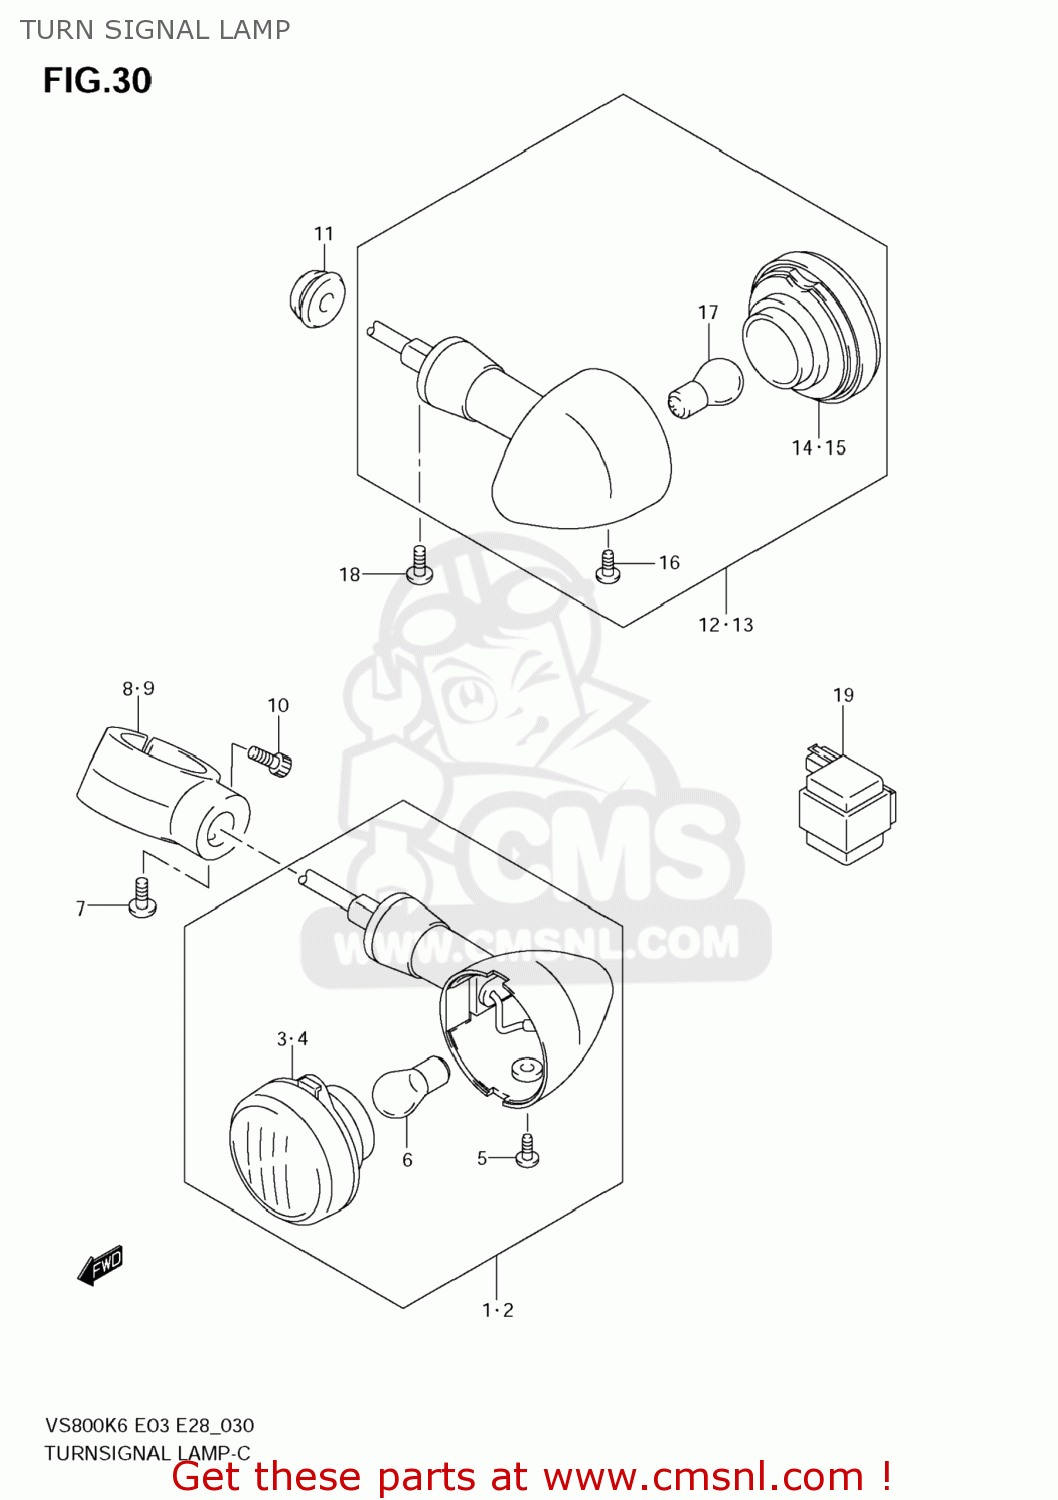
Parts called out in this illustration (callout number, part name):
1	LAMP ASSY,FR TURN SIGNAL,R
2	LAMP ASSY,FR TURN SIGNAL,L
3	LENS
4	LENS
5	SCREW(4X10)
6	BULB(12V21/5W)
7	SCREW
8	BRACKET,FR TURNSIGNAL LAMP,R
9	BRACKET,FR TURNSIGNAL LAMP,L
10	BOLT
11	GROMMET
12	LAMP ASSY,RR TURNSIGNAL,R
13	LAMP ASSY,RR TURNSIGNAL,L
14	LENS
15	LENS
16	SCREW(4X10)
17	BULB(12V21W)
18	SCREW
19	RELAY ASSY
